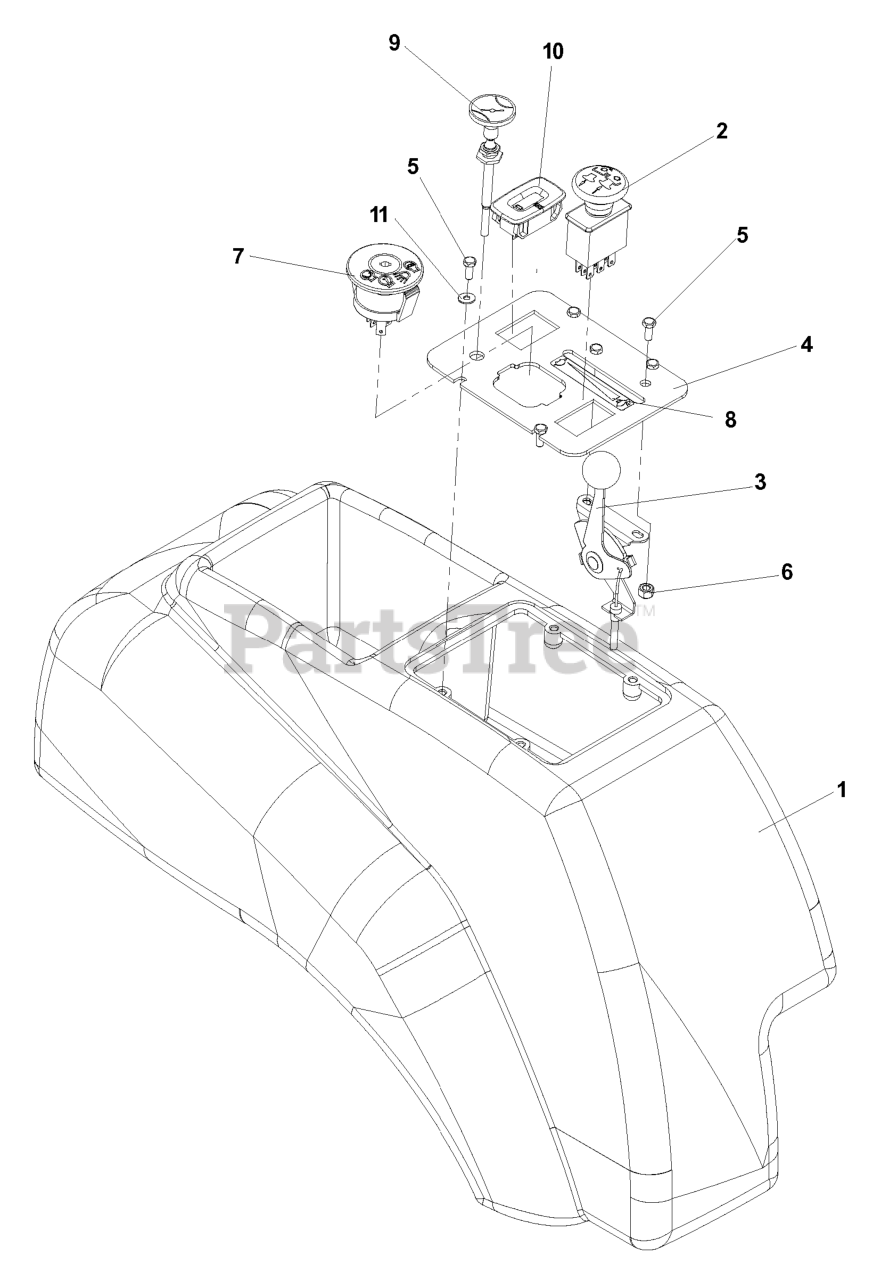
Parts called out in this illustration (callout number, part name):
1	FENDER CONSOLE
2	RP.SWITCH, BLADE
3	THROTTLE CABLE
3	THROTTLE CONTROL W/BALL KNOB
4	CONSOLE PLATE, BLACK
5	HCS #10-24 X 1/2
6	NUT 10-24 NYLOC
7	RP IGNITION SWITCH
8	DECAL, THROTTLE
9	CHOKE CABLE
9	CHOKE CONTROL, COMPLETE
10	HOUR METER
11	WASHER #10
